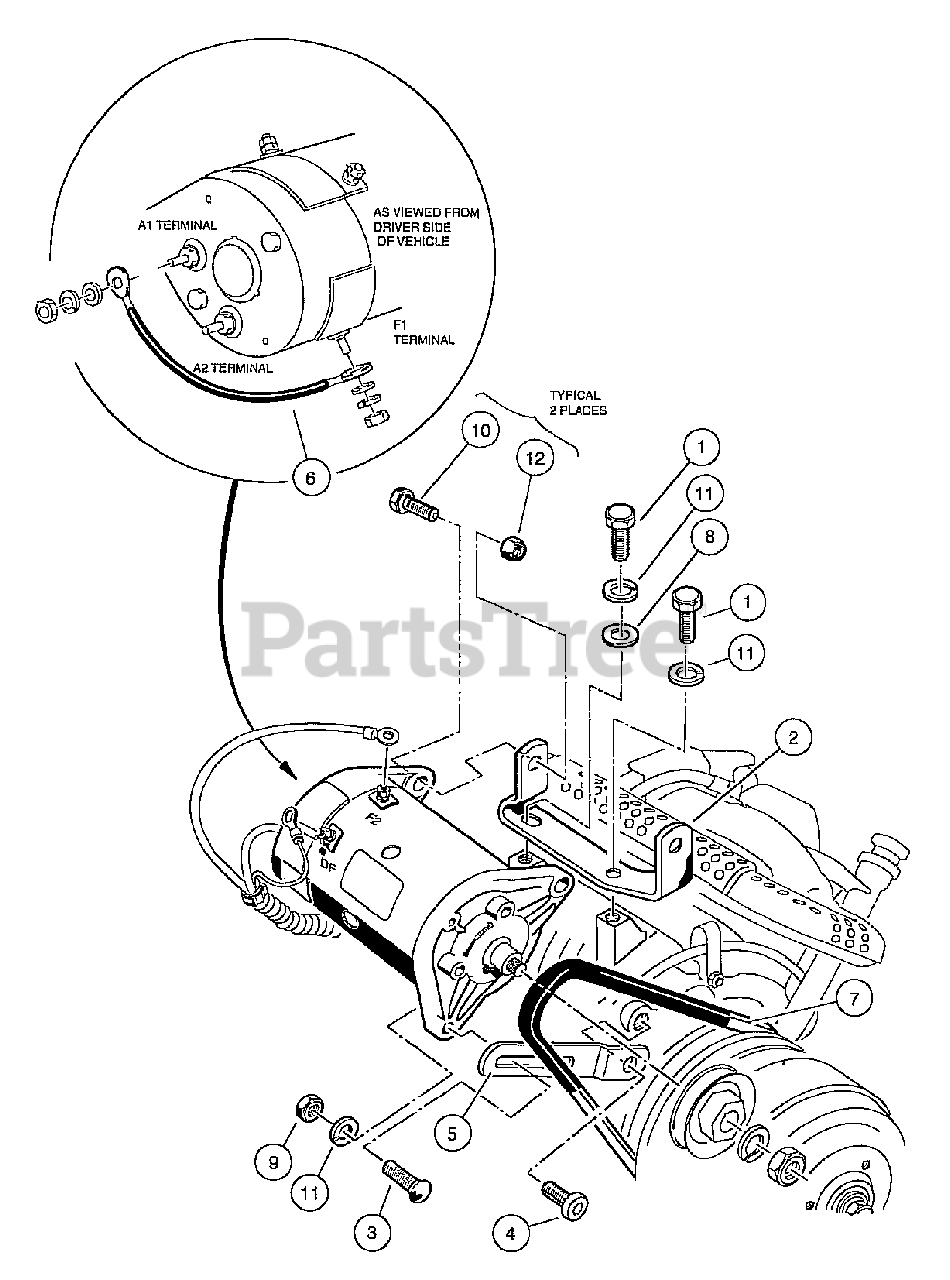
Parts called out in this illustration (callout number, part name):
1	Screw, M8-125 X 22 Hex Gr.8.8
2	Bracket, Starter/Generator Mounting (FE290)
3	Bolt, Carriage, 5/16-18
4	Screw, M8-1.25 X 18mm Torx
5	Bracket, Starter/Generator Adjustment
6	Wire Assy, #6 Green
8	Washer, 5/16 Type A Flat
9	Nut, 5/16-18 Hex
10	Bolt, 3/8-16 X 1.25 Hex Head
11	Lockwasher, 5/16 Split
12	Locknut, 3/8-16 Hex
